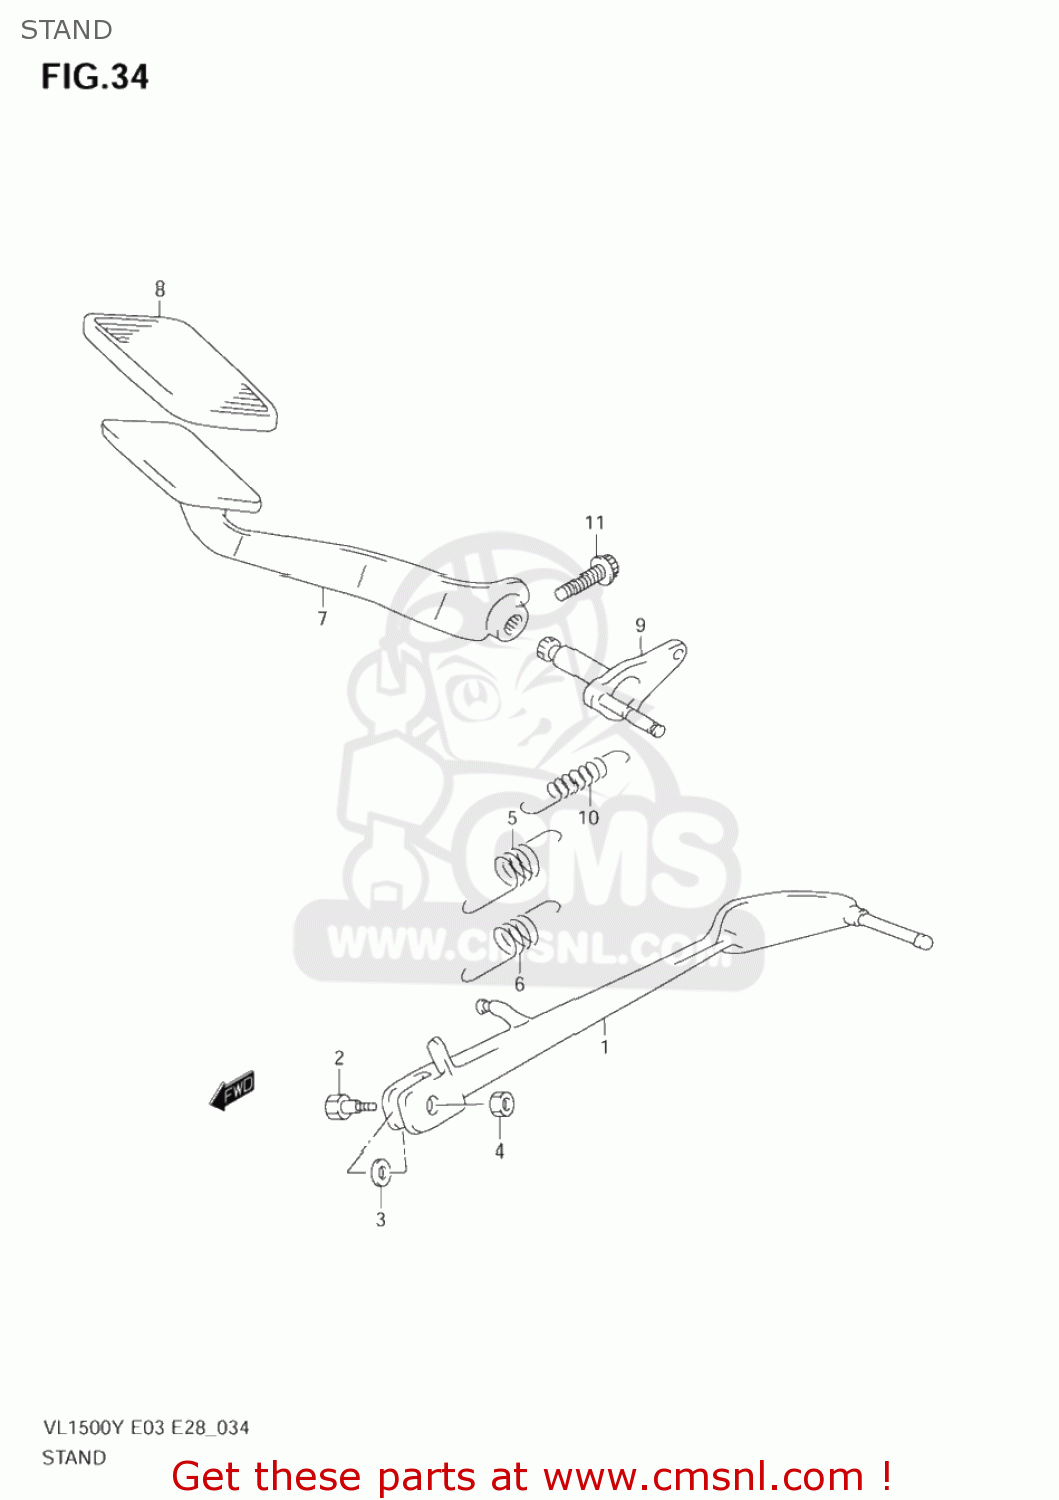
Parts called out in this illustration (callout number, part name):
1	STAND,PROP
2	BOLT(10X34)
3	SHIM
4	NUT
5	SPRING
6	SPRING
7	PEDAL,BRAKE
8	RUBBER,BRAKE PEDAL
9	ARM,BRAKE ROD
10	SPRING
11	BOLT,OIL PAN
